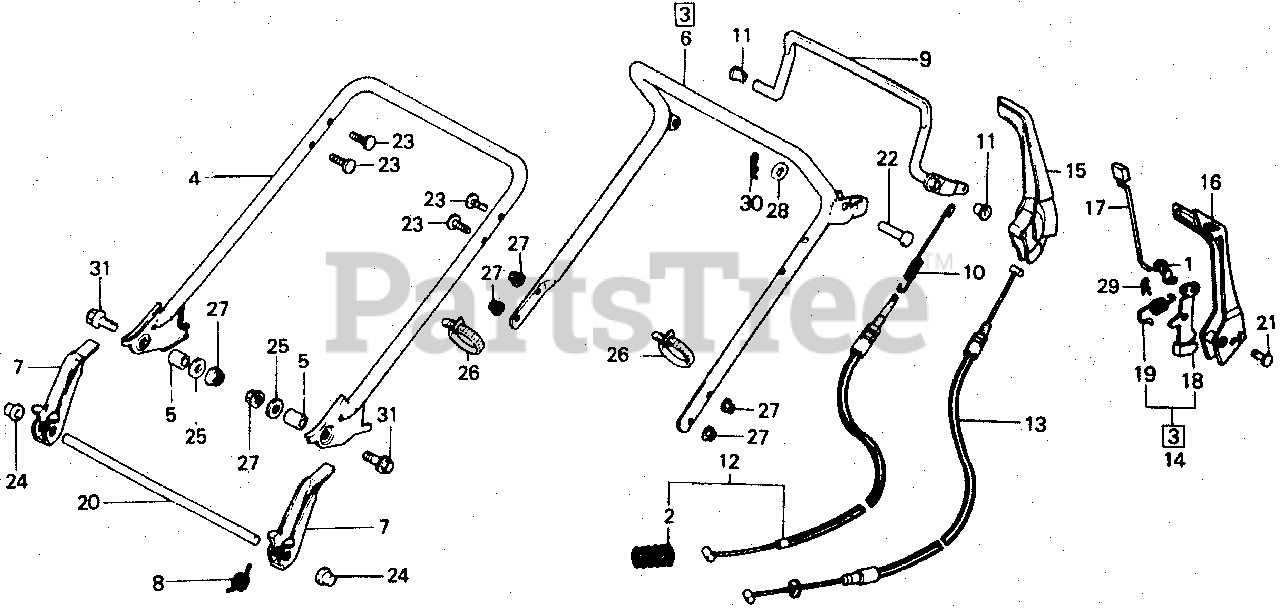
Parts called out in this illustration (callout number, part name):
1	JOINT, ROD
2	SPRING, CLUTCH RETURN (NOT AVAILABLE)
3	HANDLE SET (UPPER)
4	HANDLEBAR (LOWER) (NOT AVAILABLE)
5	COLLAR (LOWER)
6	HANDLE SET (UPPER)
7	LEVER, LOCK
8	SPRING, HANDLE (NOT AVAILABLE)
9	LEVER, CLUTCH (NOT AVAILABLE)
10	SPRING, CLUTCH (NOT AVAILABLE)
11	BUSH, CLUTCH LEVER
12	CABLE A, CLUTCH
13	CABLE, ROTO-STOP CLUTCH
14	LEVER SET, LOCK (NOT AVAILABLE)
15	LEVER, ROTO-STOP CLUTCH
16	LEVER, ROTO-STOP (NOT AVAILABLE)
17	ROD, RATCHET PUSH (NOT AVAILABLE)
18	LEVER, LOCK
18	LEVER, LOCK (NOT AVAILABLE)
19	SPRING, RATCHET RETURN
20	SHAFT, SHIELD
21	PIN, SEAT HINGE
22	PIN, CLUTCH LEVER (NOT AVAILABLE)
23	BOLT, HANDLE HOLDER (8X36)
25	WASHER (23X8.3X3.2)
26	BAND, WIRE
27	NUT, FLANGE (8MM)
28	WASHER, PLAIN (8MM)
29	PIN, LOCK (6MM)
30	PIN, LOCK (8MM)
31	BOLT, FLANGE (8X32)
